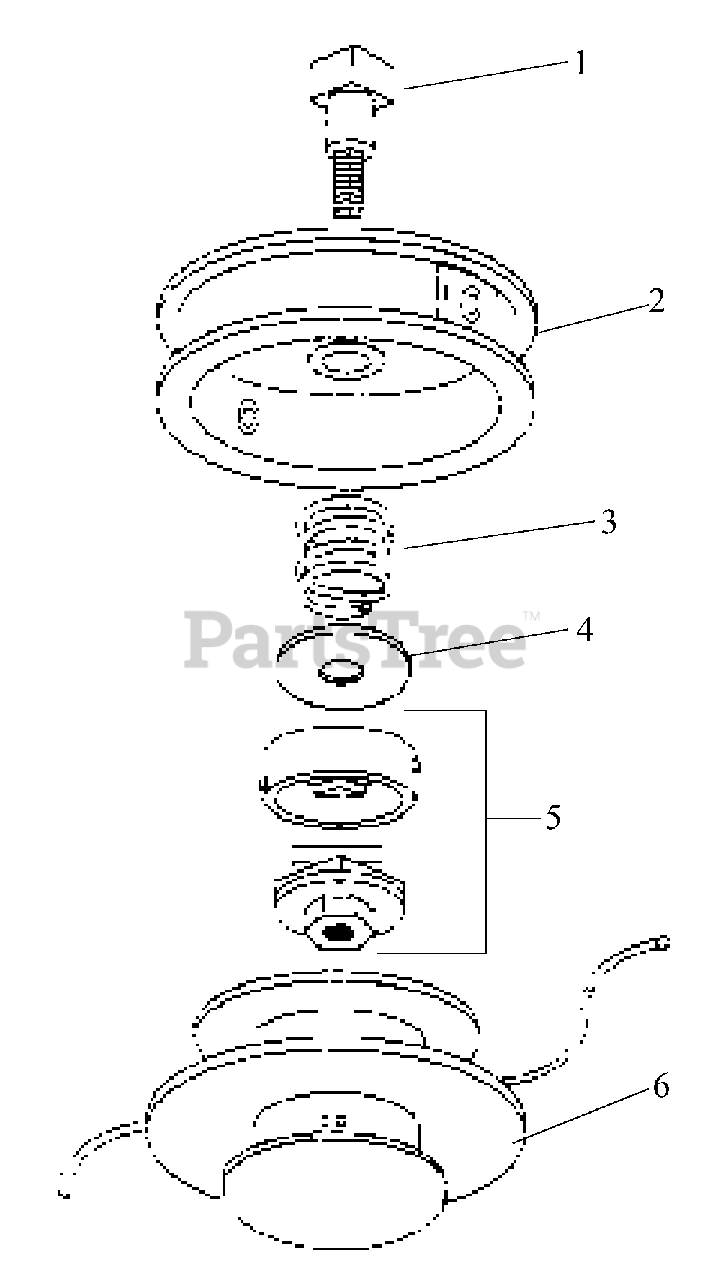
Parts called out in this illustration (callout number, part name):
1	Bolt, Shaft
2	Housing, Spool
3	Spring, Spool
4	Washer, Spring
5	Cam Asm.
P-UN30LH	String Trimmer Semi Matic Head
